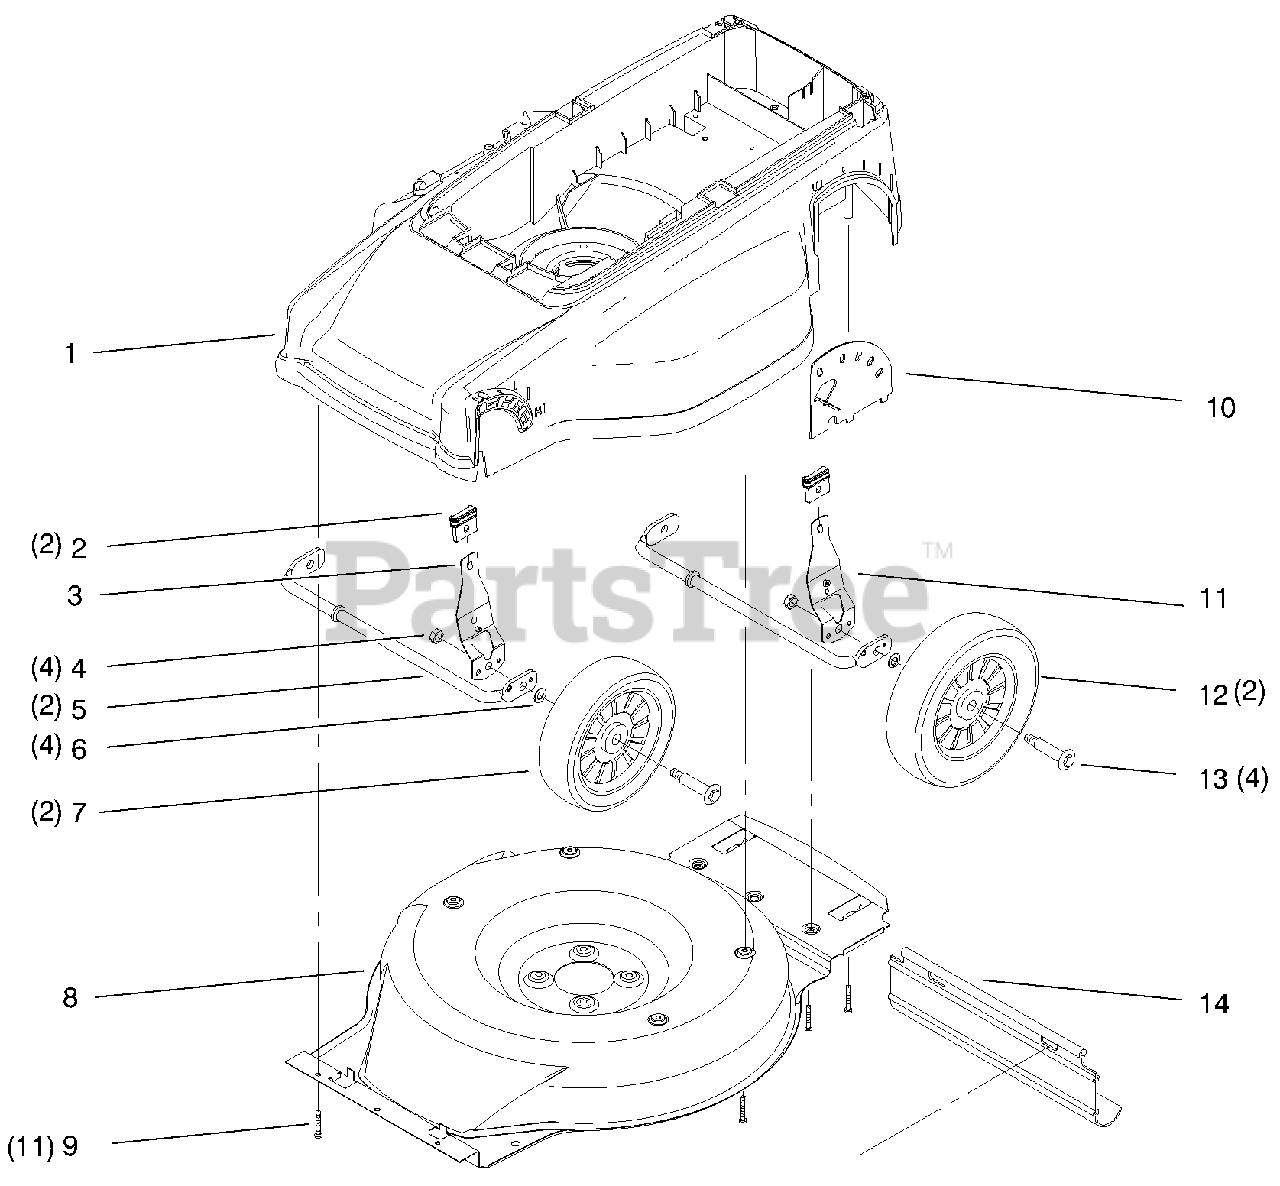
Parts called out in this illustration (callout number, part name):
2	Knob-Height Adjust
3	ASM-Front HOC Lever
4	Nut-Lock
7	ASM-Wheel
8	ASM-Liner
9	Screw-PPH
10	Plate-HOC
11	ASM-Rear HOC Lever
12	ASM-Wheel
13	Bolt-Shoulder
14	Trailing Shield
